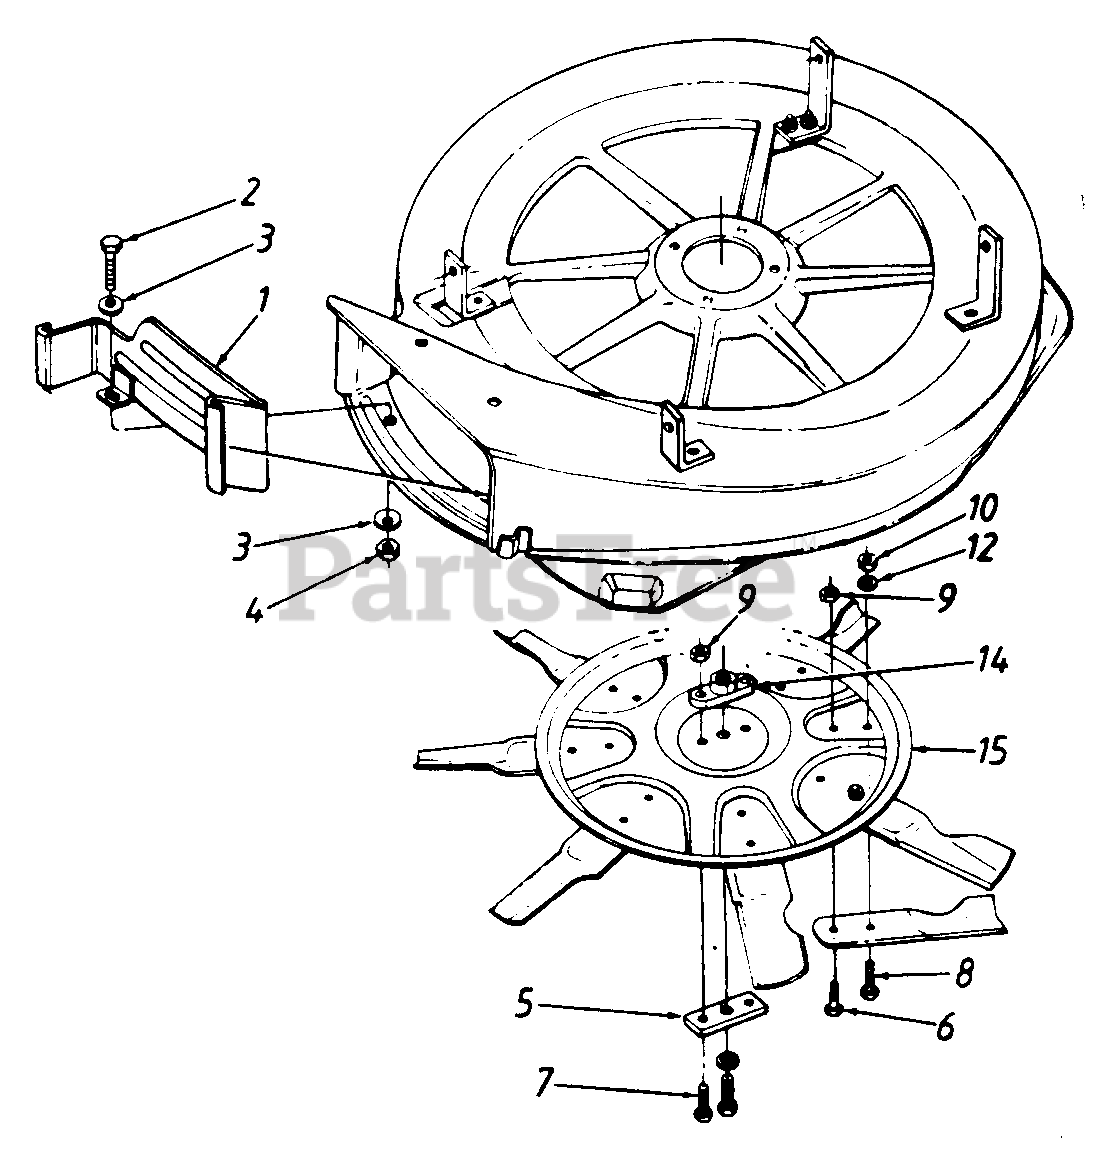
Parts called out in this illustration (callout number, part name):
1	Mulching Baffle Ass'y.
2	Hex Bolt 5/16-18 x .5"
3	Bell-Wash..325" I.D.
4	Hex L-Nut 5/16-18 Thd.
7	Hex Bolt 5/16-24 x 1.25n Lg. (Grade 5)
8	Hex Bolt 3/8-24 x .88" Lg
9	Hex L-Nut 5/16-24 Thd.
10	Hex L-Nut 3/8-24 Thd. (Grade 5)
12	Fl-Wash. .406" I.D. x .75"
14	Blade Adapter
15	30" Mulching Blade Disc
